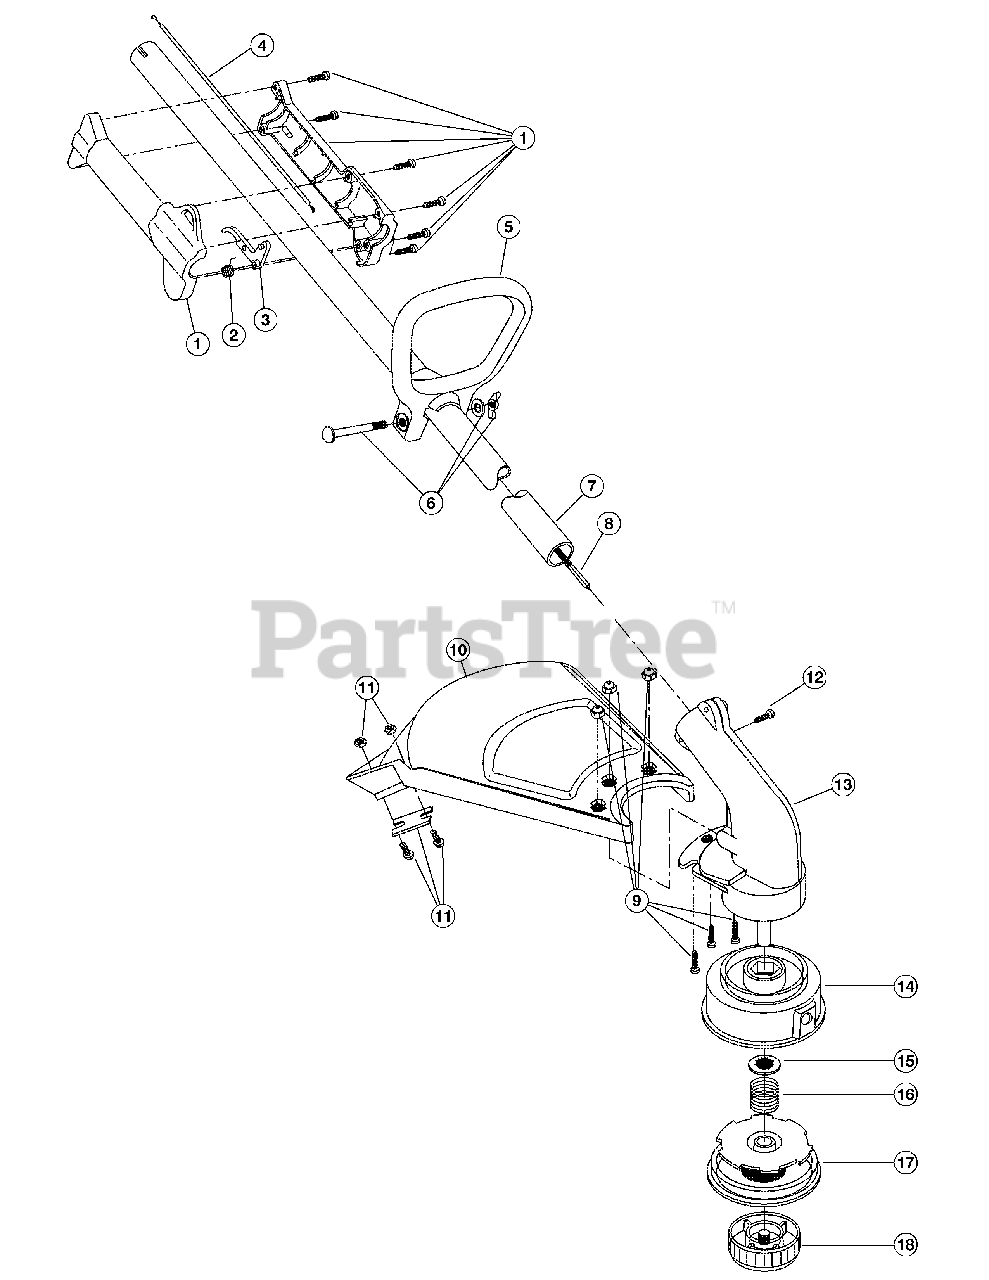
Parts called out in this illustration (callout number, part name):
1	Throttle Housing Assembly (includes 2-3)
2	Throttle Trigger Spring
3	Throttle Trigger
4	Throttle Cable
5	D-Handle (includes 6)
6	D-Handle Hardware Assembly
7	Drive Shaft Housing Assembly
8	Flexible Drive Shaft
9	Guard Mounting Screw Assembly
10	Guard Assembly (includes 11)
11	Blade Assembly
12	Anti-Rotation Screw
13	Gearbox Assembly (includes 14-18)
14	Outer Spool and Eyelet Assembly (includes 15)
15	Retainer
17	Inner Reel
18	Bump Head Knob Assembly
